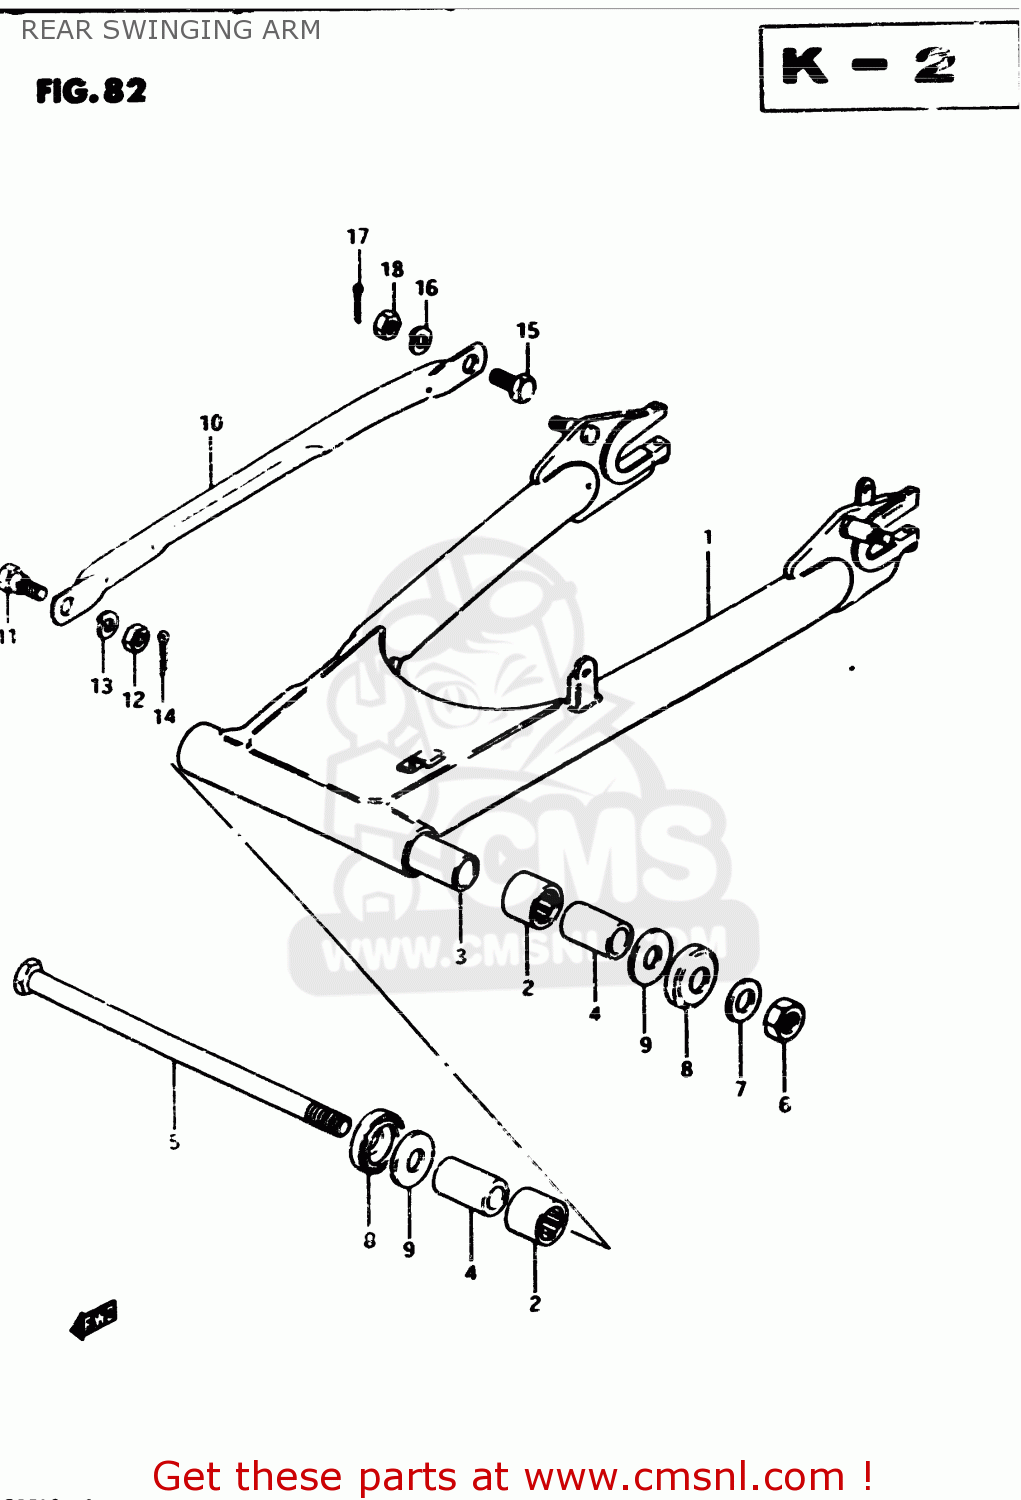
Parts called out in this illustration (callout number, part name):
1	ARM,REAR SWING
2	BEARING(22X29X30)
3	SPACER,SWINGINGARM CTR
4	SPACER,RR SWGARM PIVOT
5	SHAFT,REAR SWING ARM
6	NUT 14MM
7	WASHER
8	CVR,RR SWGARM DUST SEAL(OD:40)
9	WASHER(14.2X34X1)
10	TORQUE LINK,REAR
11	BOLT(10X24.5)
12	NUT
13	LOCK WASHER
14	PIN 20X20
15	BOLT(10X31)
16	LOCK WASHER
17	PIN 20X20
18	NUT
